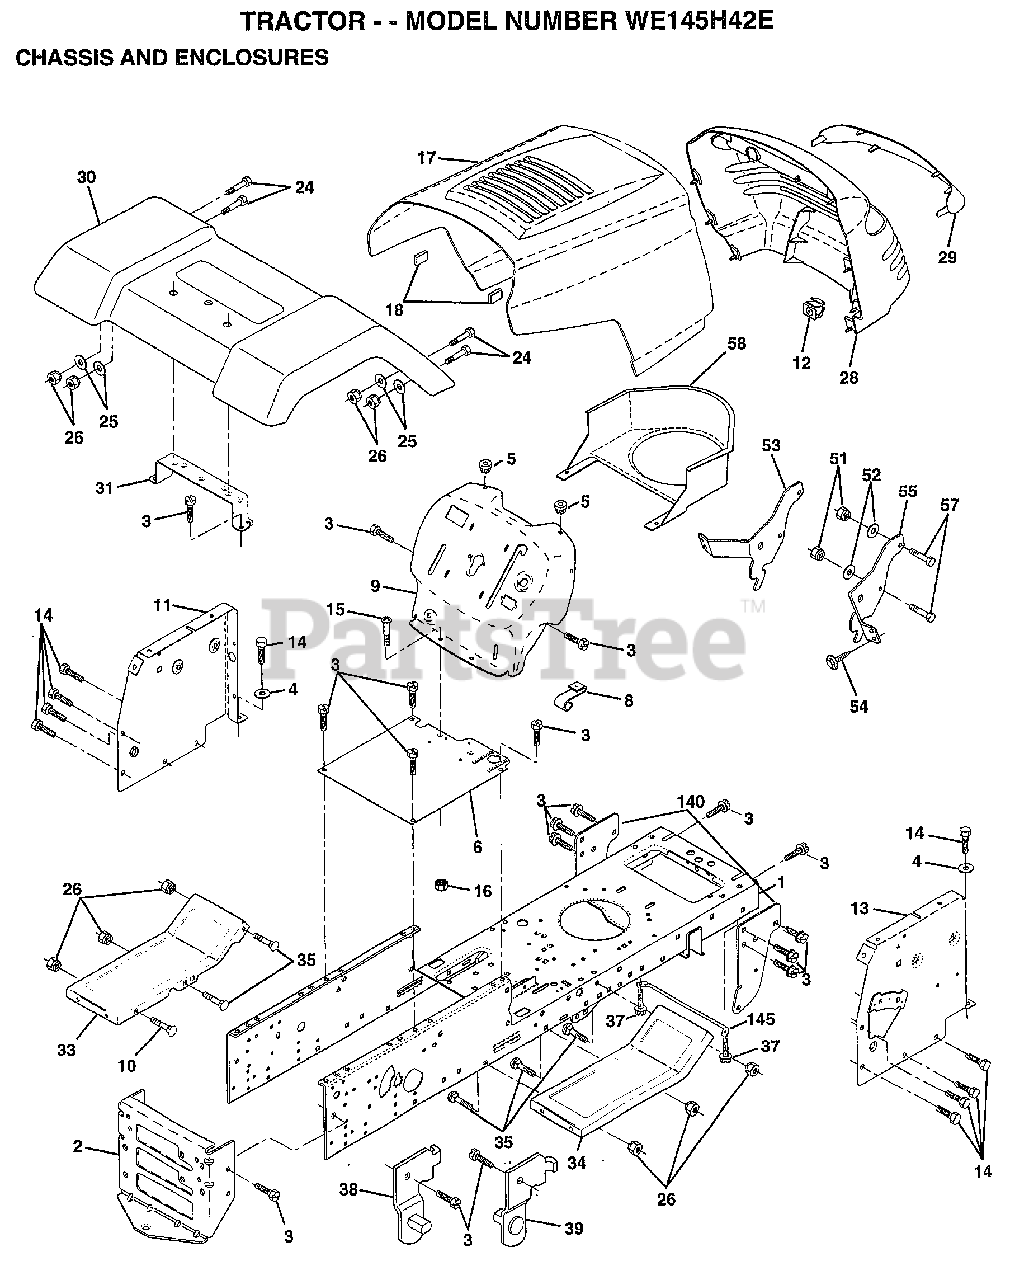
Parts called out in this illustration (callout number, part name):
1	CHASSIS.STAMPING
3	SCREW
4	WASHER
5	BUMPER-HOOD/DASH
6	SADDLE
8	CLIP.RETAINER
9	DASH SILKSCREEN
11	"PANEL-DASH,LH"
12	CLIP.TINNERMAN
13	PANEL.ASM.SLKSCR.DASH.RH
14	SCREW LT
15	SCREW
17	HOOD.STEEL.ASSY
24	BOLT
25	WASHER
26	NUT
28	GRILLE-MS428
29	LENS.GRILLE.PRIVATE LABEL
31	BRKT FENDER
33	FOOTREST.LH.PERF.
34	FOOTREST.RH.PERF.
35	BOLT
37	SCREW LT
38	BRACKET ASM LH
39	BRACKET ASM RH
51	NUT
52	WASHER
53	BRACKET.GRILLE.LH
54	SCREW.HEX.WS.HD
55	BRACKET.GRILLE.RH
58	AIR DUCT
140	BRKT SUSPENSION
145	"ROD POVOT,CHASSIS"
